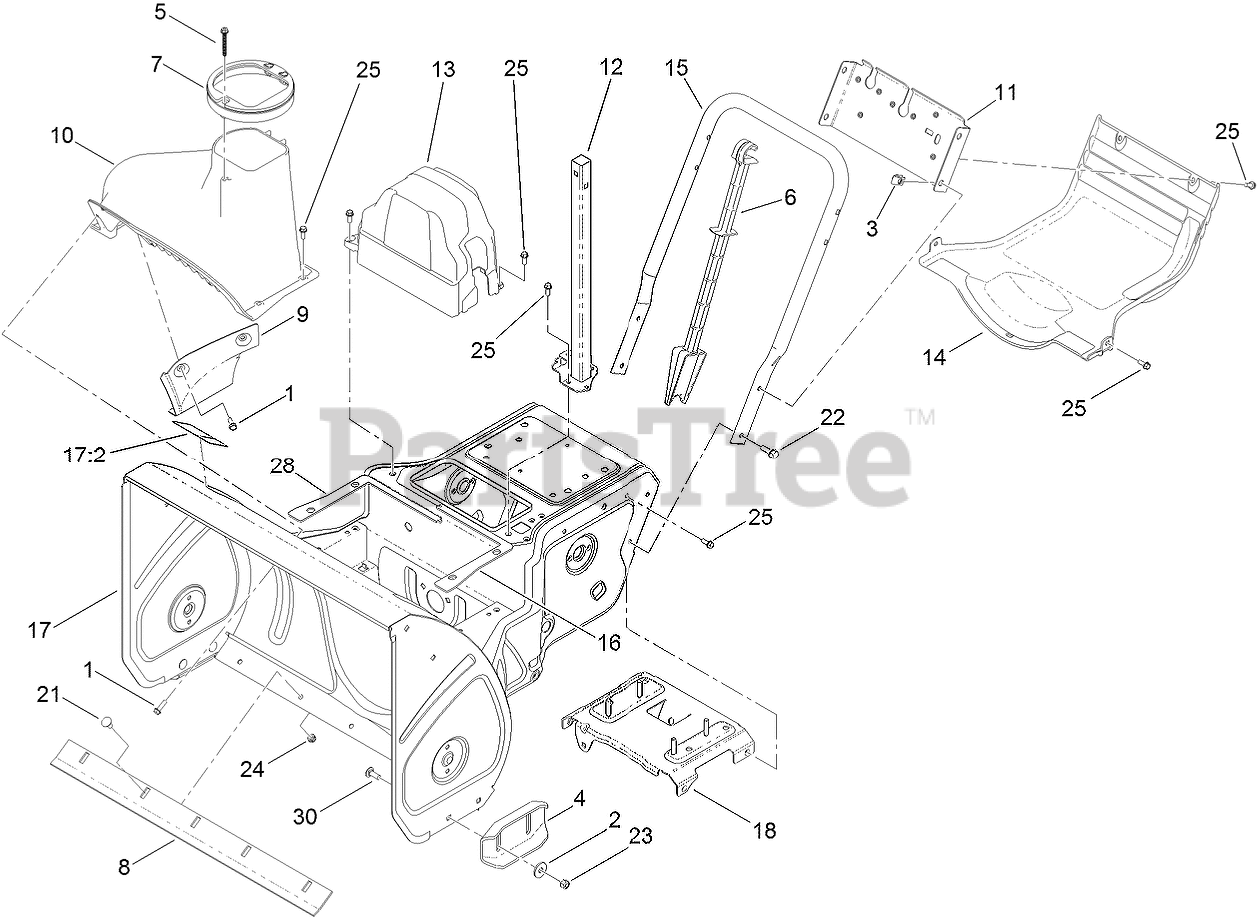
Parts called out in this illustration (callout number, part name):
1	SCREW-HWH
2	WASHER
3	NUT-U
5	SCREW-HWH, PLASTITE
6	STICK-CLEANOUT
7	GUIDE-CHUTE
8	SCRAPER-26 INCH
9	COVER-LINER
11	BRACE-FRAME
12	SUPPORT-CHUTE
13	COVER-BELT
14	COVER-LOWER
15	HANDLE-LOWER
16	SEAL-HOUSING, LH
17	FRAME ASM
17:2	DECAL-DANGER, AUGER
18	PLATE-STUD ENGINE
21	SCREW-CARR
22	SCREW-HHF
23	NUT-LOCK, NI
24	NUT-LOCK, NI
25	SCREW-HWH
28	SEAL-HOUSING, RH
30	SCREW-CARR
